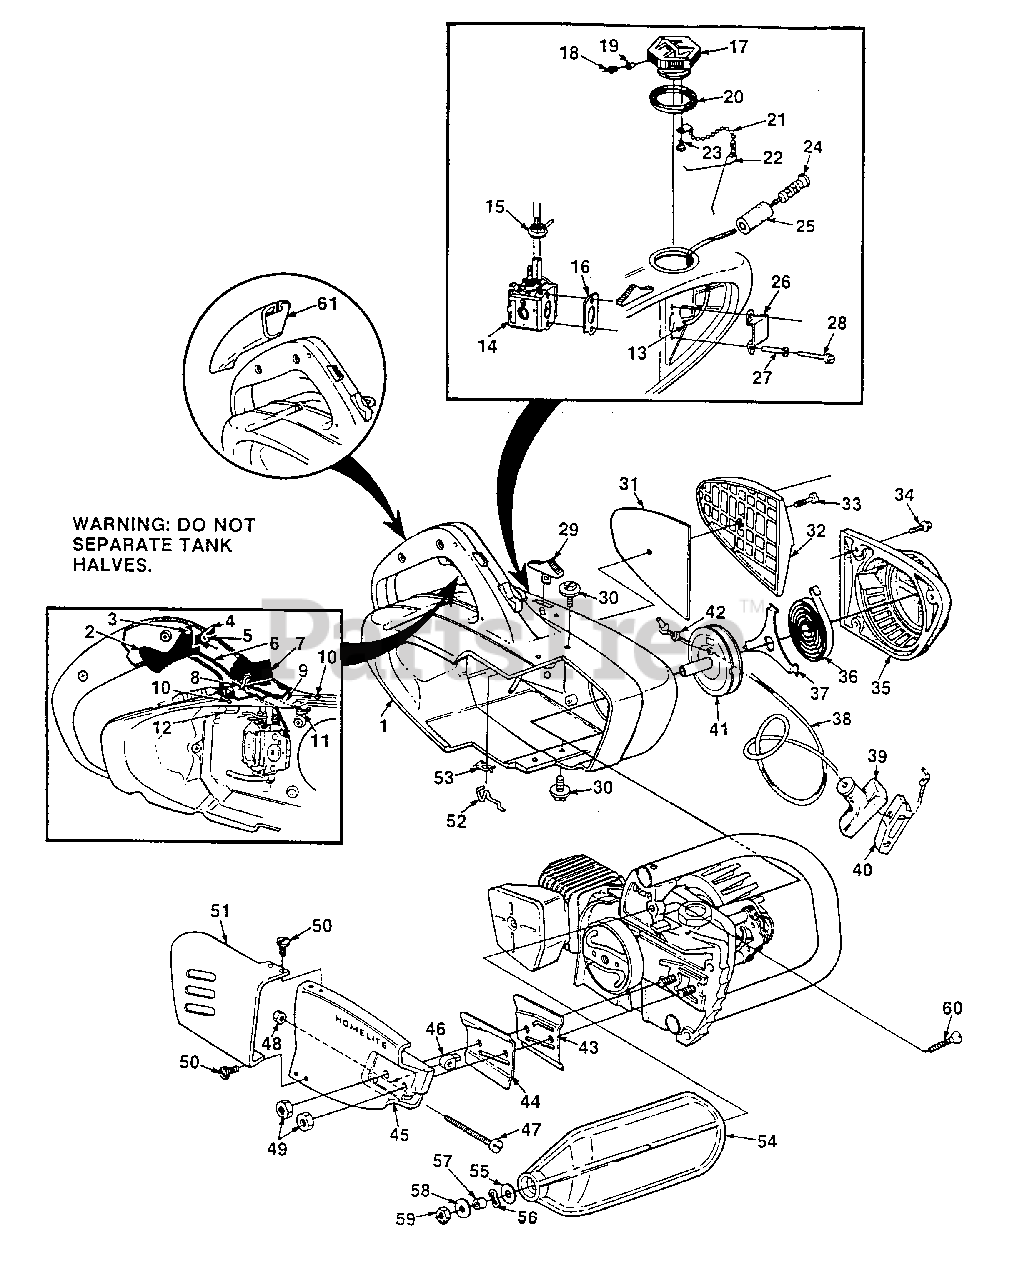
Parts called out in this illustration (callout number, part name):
1	ENGINE COVER
2	TRIGGER- Throttle
3	PIN- Trigger
4	SPRING- Trigger latch
5	PIN- Grooved
6	LINKAGE- Throttle
7	BUTTON- Stop switch
8	SPRING- Stop switch
9	LINK- Grounding switch
11	CONTACT- Grounding switch
12	CLAMP- High tension
13	TUBING- Rubber (fuel) 8"
14	CARBURETOR- Walbro HDC-54
15	DETENT- Carburetor
16	SPACER- Carburetor
17	CAP- Fuel filler
18	FILTER- Fuel cap
19	VALVE- Check
20	GASKET- Fuel filler cap
21	CHAIN- Bead
22	RETAINER
23	SCREW- Pan hd., #6 x 1/4
24	FILTER- Fuel
25	ELEMENT- Felt filter
26	DEFLECTOR- Air
27	BUSHING- Flanged
28	SCREW- Hex washer hd., 8-32 x 2
29	BUTTON- Choke
30	SCREW- Sems hex hd., 10-24 x 5/8
31	FILTER- Element air
32	COVER- Air filter
33	SCREW- Cover retaining
34	SCREW- Hex washer hd., 8-32 x 1/2
35	HOUSING- Starter
36	SPRING- Rewind
37	RETAINER- Rewind spring
38	ROPE- Starter #4 (42" long)
39	GRIP- Starter rope
40	INSERT- Rope retaining
41	PULLEY- Starter
42	WASHER- Nylon
43	PLATE- Guide bar (inner)
44	PLATE- Guide bar (outer)
45	COVER- Drivecase
46	PIN- Guide bar adjusting
47	SCREW- Guide bar adjusting
48	NUT- Hex centerlock, 10-32
49	NUT- Hex 5/16-18
50	SCREW- Pan hd., 8-32 x 3/8 (150 AOW)
51	SHIELD MUFFLER- (150 AOW)
52	ROD- Choke
53	SPRING- Choke
54	HANDGUARD
58	WASHER
59	NUT- Hex (12-24)
60	SCREW- Flat head
61	COVER- Right hand
